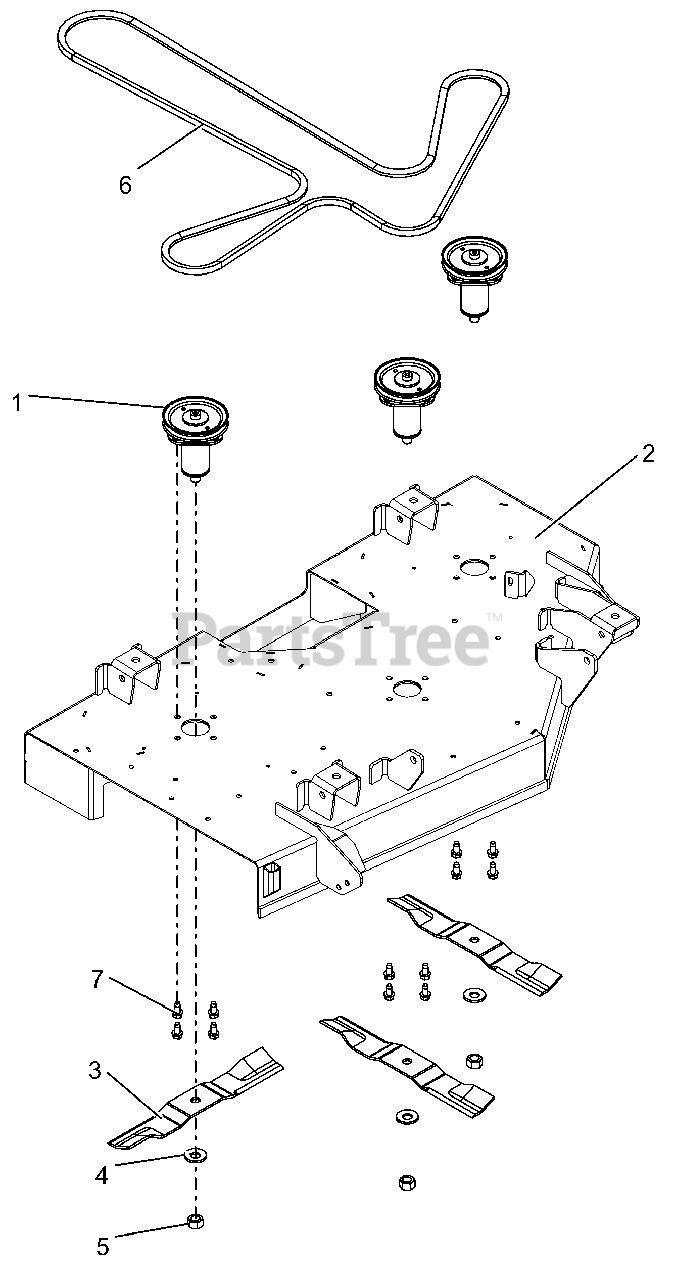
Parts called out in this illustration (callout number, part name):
1	KIT, DECK SPINDLE ASM-IKON-ZTX
2	KIT, 42" GRAVELY DECK W/DECALS
3	BLADE, MOWER 15.00"
4	WSHR-BLVL .669X1.535X.138
5	NUT-STD .625-18 ZCC
6	V-BELT, 4L-WRAPPED
7	SCR,TAP .375-16X.75 HWH TR ZCC
